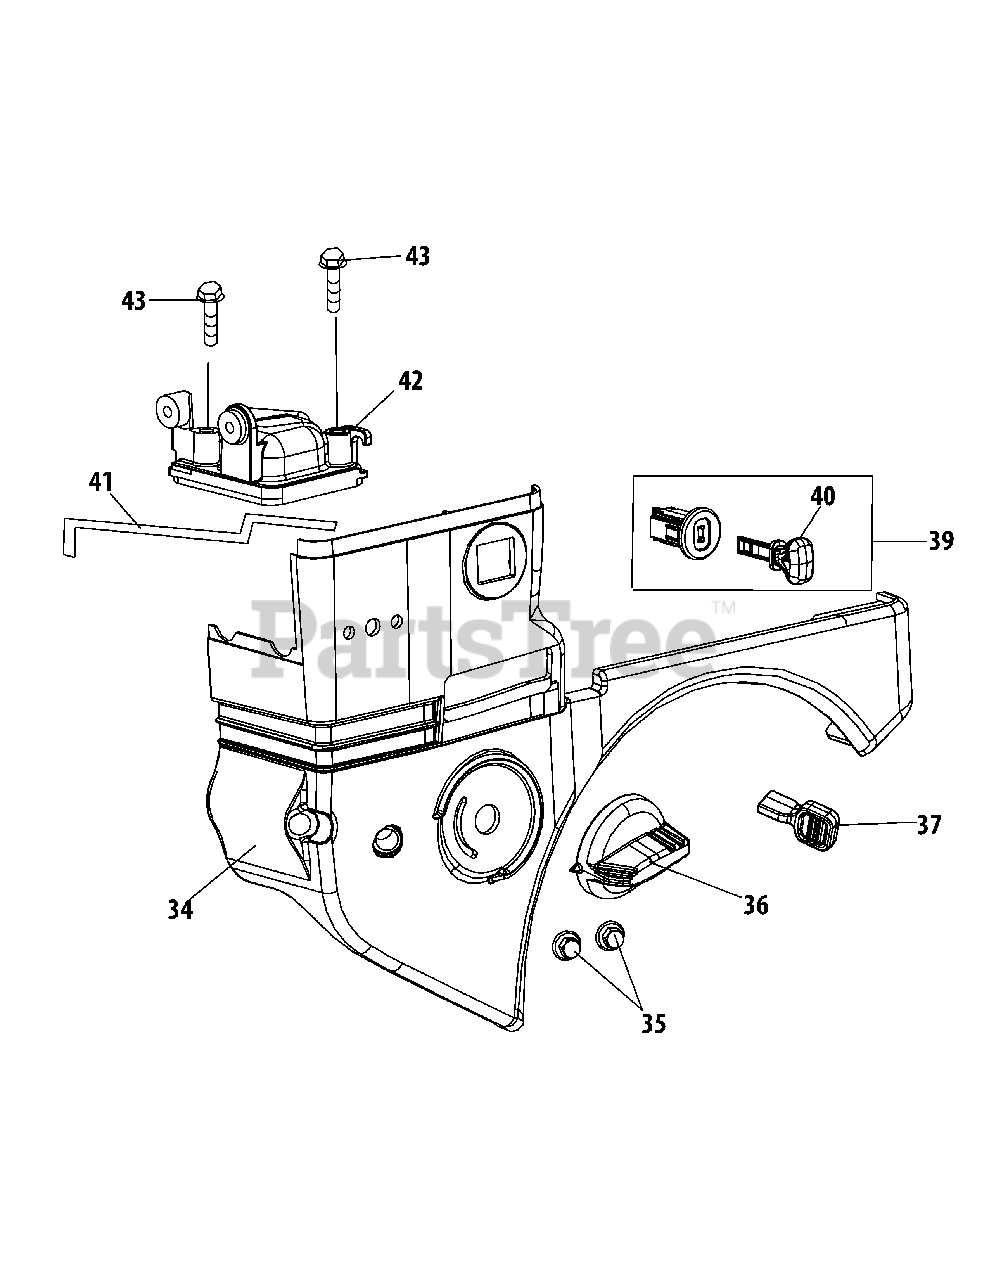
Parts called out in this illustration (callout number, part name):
34	Air Cleaner Housing
36	Choke Knob
37	Throttle Control Knob
39	Key Switch
40	Key
41	Choke Push Rod
42	Heater Box
43	Bolt M6×28
